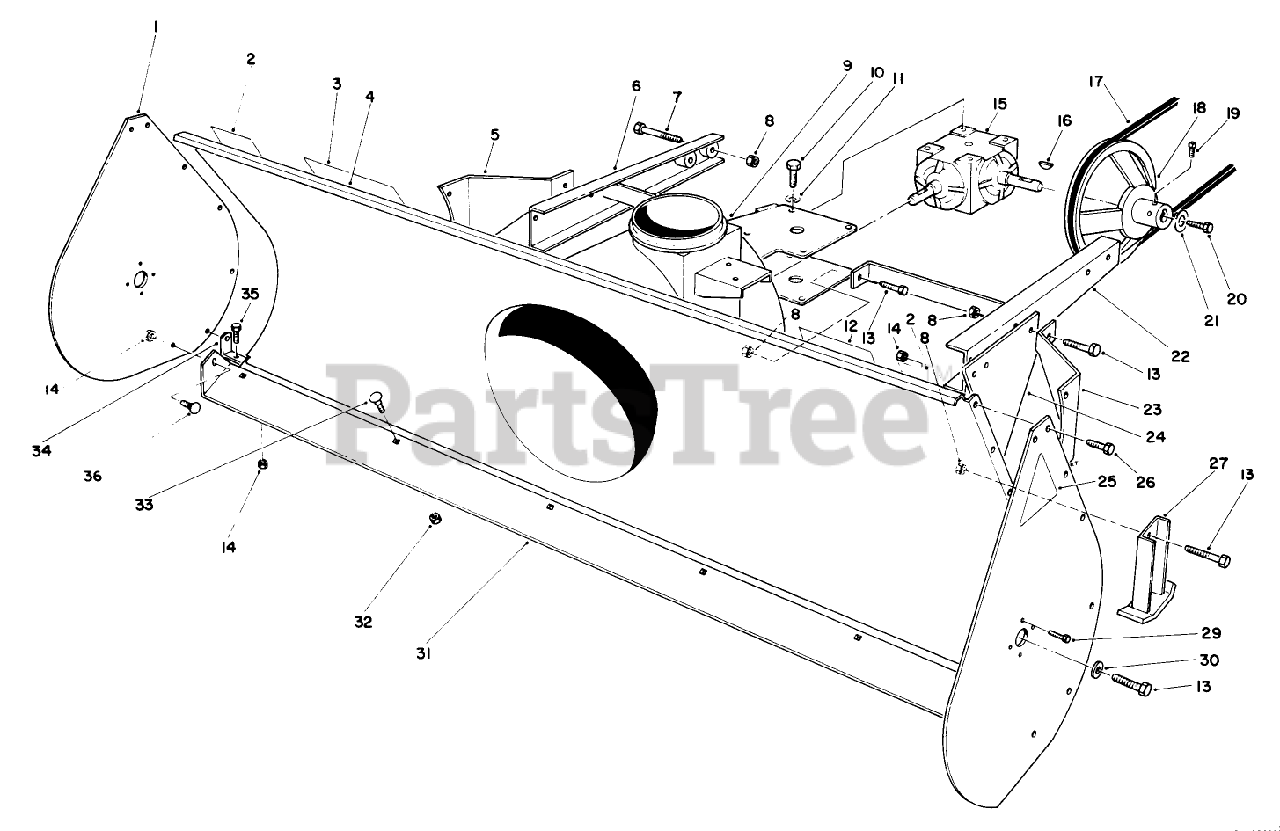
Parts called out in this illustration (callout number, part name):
1	Plate-Side
2	DECAL-WARNING, AUGER
3	Decal-Warning
4	HOUSING WA R
5	RH EXTENSION PLT R
6	RH EXT BAR WA R
7	SCREW-HH
8	NUT-LOCK, NI
9	CHUTE RING
10	SCREW-HH
11	WASHER-LOCK, INTERNAL
12	Decal-Rear Weight
13	SCREW-HH
14	NUT-LOCK, NI
15	GEARBOX
16	KEY-WOODRUFF
17	V-BELT
18	DRIVE PULLEY
19	SCREW-SET, SQH
20	BOLT 60183
21	WASHER-FLAT
22	LH EXT BAR WA R
23	LH EXTENSION PLT R
24	SKID MTG PLT R
25	AUGER SIDE PLT DECAL
26	SCREW-HH
27	SKID WA R
29	SCREW-HH
30	WASHER
31	Blade-Scraper
32	NUT-LOCK, NI
33	SCREW-CARR
34	BLADE SUPPORT BRKT R
35	SCREW-HH
36	SCREW-CARR
